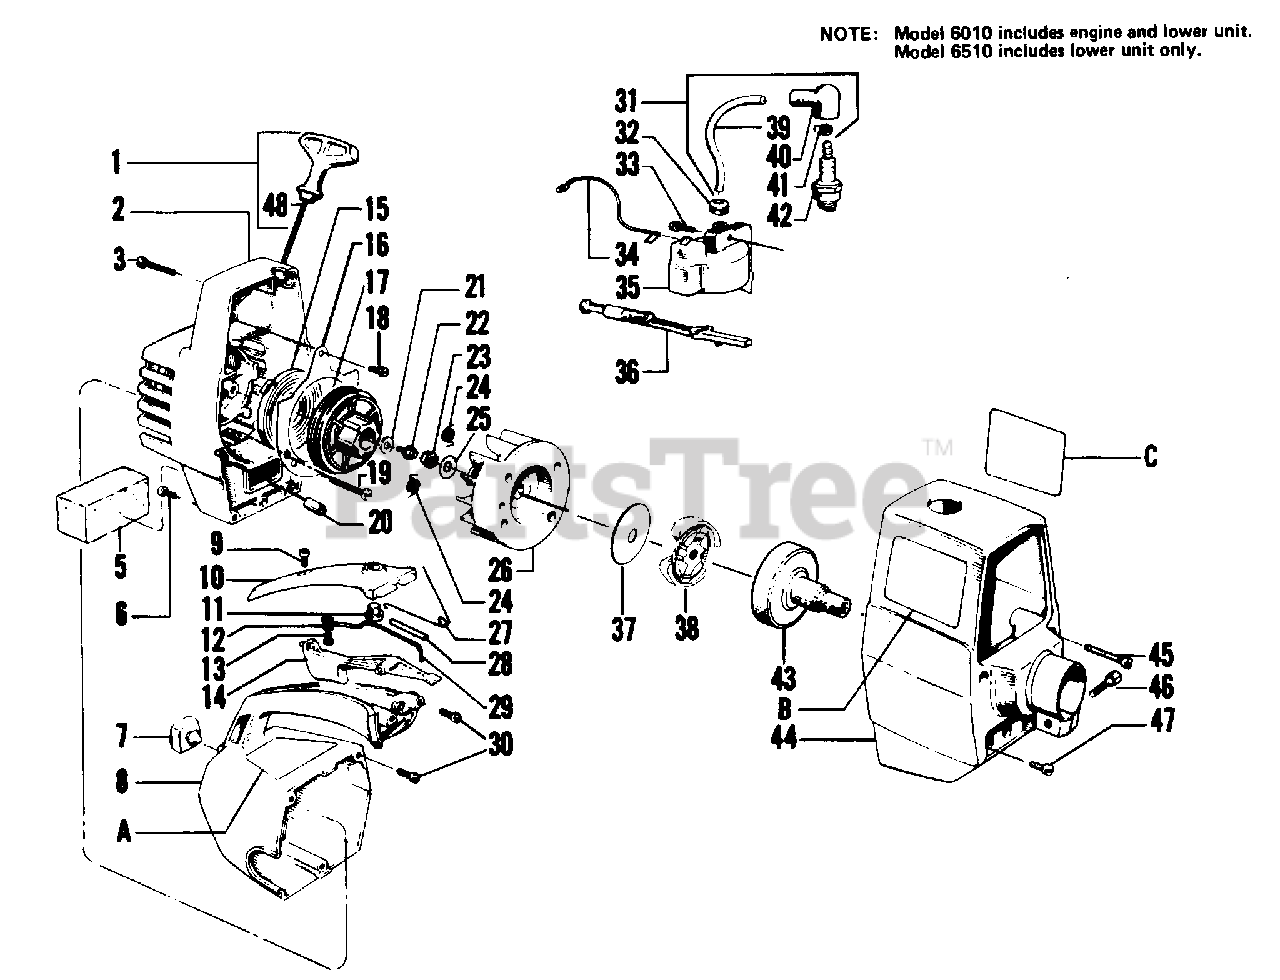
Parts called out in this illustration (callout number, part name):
2	Fan Housing Kit (Inc. 16, 18, 19, 20, 28)
3	Screw - 10 - 24 x 1-1/2 - Sems - Fan Housing - Top
5	Air Filter
6	Screw - 10 - 24 x 5/8 - Sems - Fan Housing - Bottom
7	Bumper - Fuel Tank Housing
8	Handle & Fuel Tank Housing
9	Screw - 8 - 16 x 3/4 - Pan Hd. - Handle Cover
10	Handle Cover
11	Button - Kill Switch
12	Washer - Kill Switch
13	Screw - 8 - 16 x 3/8 - Pan. Hd. - Kill Switch
14	Trigger - Throttle
16	Air Baffle - See Service Ref. 6.
18	Screw - # 10 x 3/8 - Pan Hd. - Air Baffle - See Service Ref. 6.
19	Screw - 10 - 24 x 1-3/16 - Plastite - See Service Ref. 6.
21	Washer - Starter Pulley
22	Screw - # 10 - 3/4 - Hex Washer Hd. - Starter Pulley
23	Nut - Flywheel - 5/16 - 24
24	Spring - Starter Dog
25	Washer - Flywheel
26	Flywheel Assembly (Inc. # 24)
27	Trigger - Spring
28	Insulation - Switch Spring
29	Spring - Kill Switch
30	Screw - 10 - 14 x 3/4 - Pan Hd. - Fan Hsg. to Handle and Fuel Tank
31	BEVEL GEAR COMPLETE
32	Grommet - Plug Wire
33	Screw - 8 - 32 x 3/4 - Fil. Hd. - Ignition Module
34	Lead Wire Switch
35	Kit - Ignition - Module
36	Knob - Choke
37	Kit - Clutch Washer - See Service Ref. 5
38	Kit - Clutch Ass'y. - See Service Ref. 1 & 5 (Inc. Clutch Washer)
39	High Tension Lead Wire
40	Boot - Spark Plug
41	Connector - Spark Plug Lead
42	Spark Plug
43	Coupling and Bearing Assembly
45	Screw - 10 - 24 x 1-1/3 - Fil. Hd. - Shroud (Top)
46	Bolt - #1/4 - 20 x 1" Pinch Clamp
47	Screw - 10 - 24 x 5/8 - Fil. Hd. - Shroud (Bottom)
48	Rope (3.5 Ft.)
A	Decal - Starting Instructions
B	Decal - Shroud (Right)
C	Decal - Shroud (Left)
